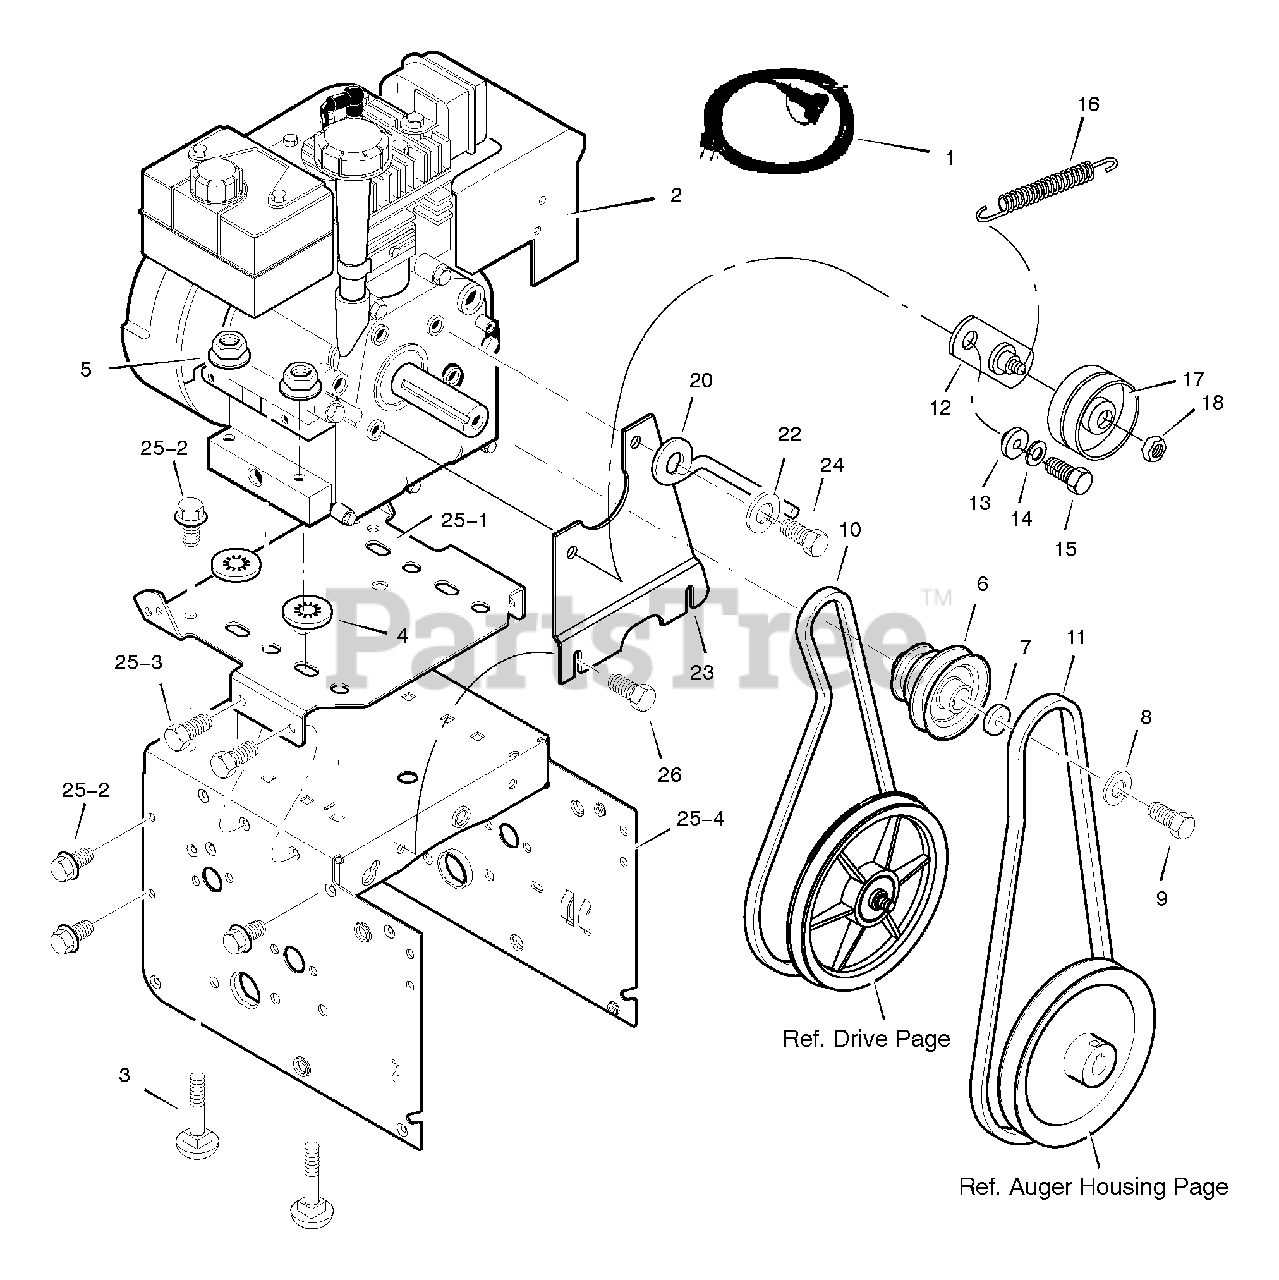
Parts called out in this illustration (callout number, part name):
1	CORD, Electric, 10FT. 110V
2	ENGINE *
3	BOLT, CARRIAGE 5/16-18
4	RETAINER, PUSH
5	NUT, HEX 5/16-18
6	PULLEY, ENGINE
7	WASHER
8	WASHER .38ID
9	SCREW, 3/8-24 x 1.00
10	BELT, DRIVE V 3L
11	BELT, AUGER V 4L
12	BRACKET ASSEMBLY, IDLER
13	BUSHING, IDLER BRACKET
14	WASHER, SPLIT
15	SCREW 5/16-24 X 1.00
16	SPRING, IDLER TRACTION DRIVE
17	PULLEY, IDLER
18	NUT, JAM 3/8-16
20	GUIDE, BELT
22	WASHER, SPTLK .31X.58X.08
23	PLATE, ANTI VIBRATION
24	SCREW, 5/16-24 x 1.00
25	FRAME ASSEMBLY
25-1	PLATE, ENGINE MOUNT
25-2	SCREW, TAP 1/4-20 X .63
25-3	SCREW, TAP 5/16-18 X .50
25-4	FRAME, MOTOR BOX
